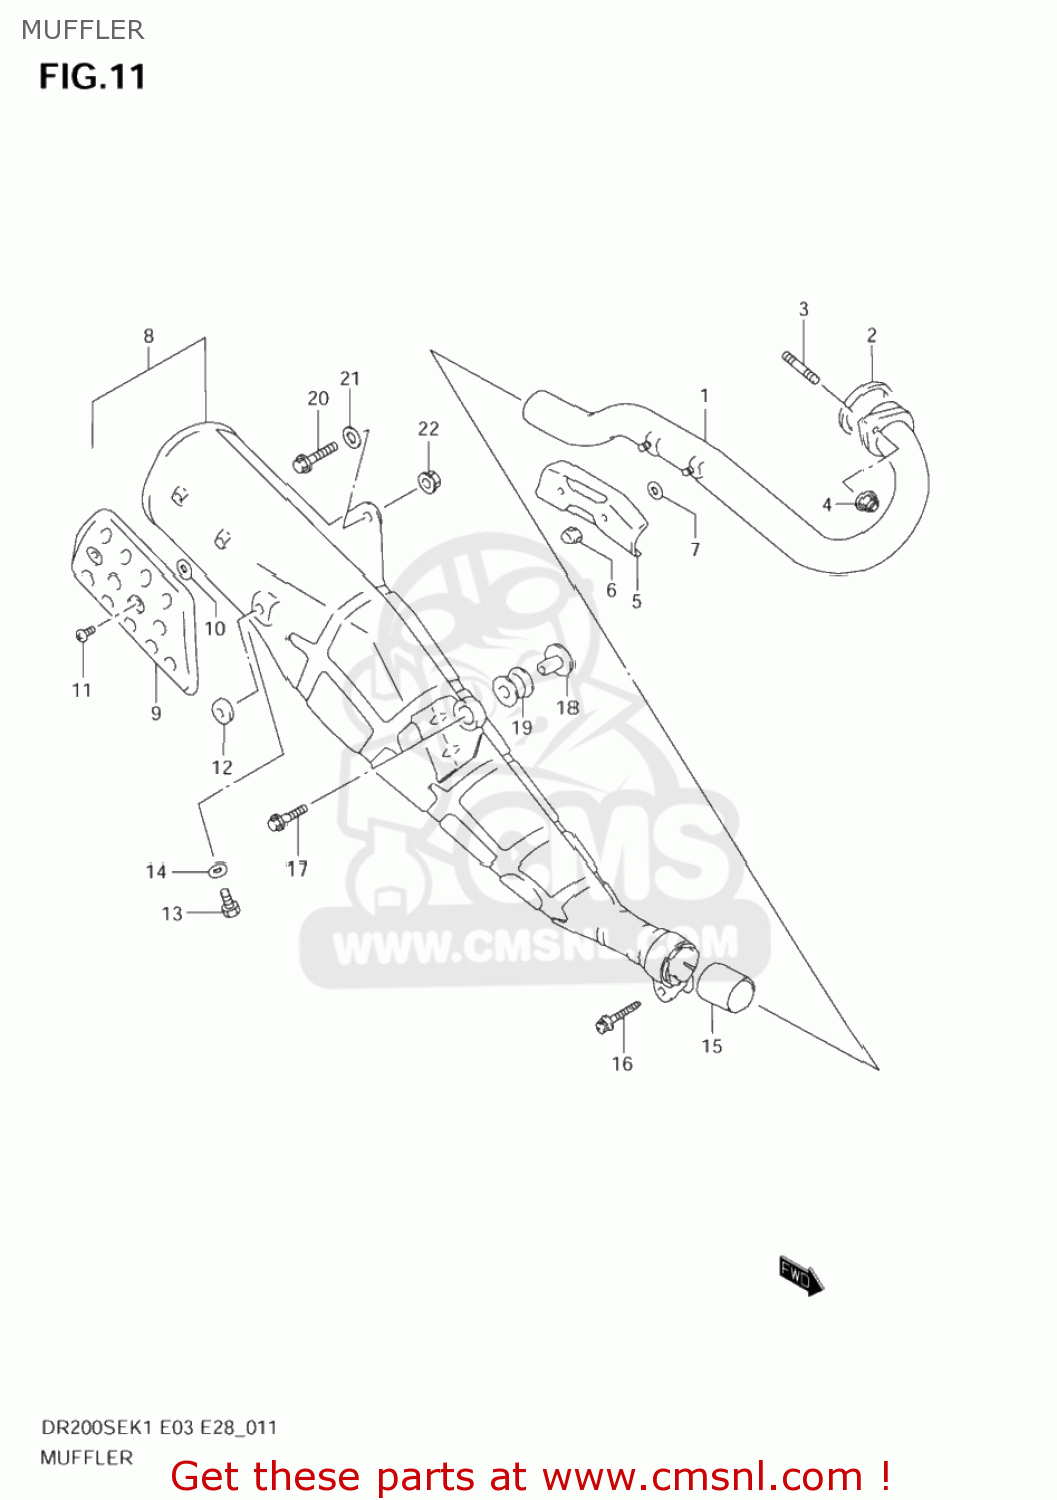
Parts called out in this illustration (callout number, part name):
1	PIPE,EXHAUST
2	GASKET,EXHAUST PIPE (NAS)
3	STUD 8X25
4	NUT
5	COVER,EXHAUST PIPE
6	NUT
7	GASKET(6X16X1.4) (NAS)
8	MUFFLER ASSY
9	COVER,MUFFLER
10	GASKET(5.8X13X1.4) (NAS)
11	SCREW(6X10)
12	CUSHION
13	PLUG(12X9)
14	GASKET(12.1X16.2X3.7) (NAS)
15	GASKET,2ND MUFFLER (NAS)
16	BOLT
17	BOLT(8X35)
18	SPACER(8.6X12X17.5)
19	CUSHION
20	BOLT(8X35)
21	WASHER
22	NUT
